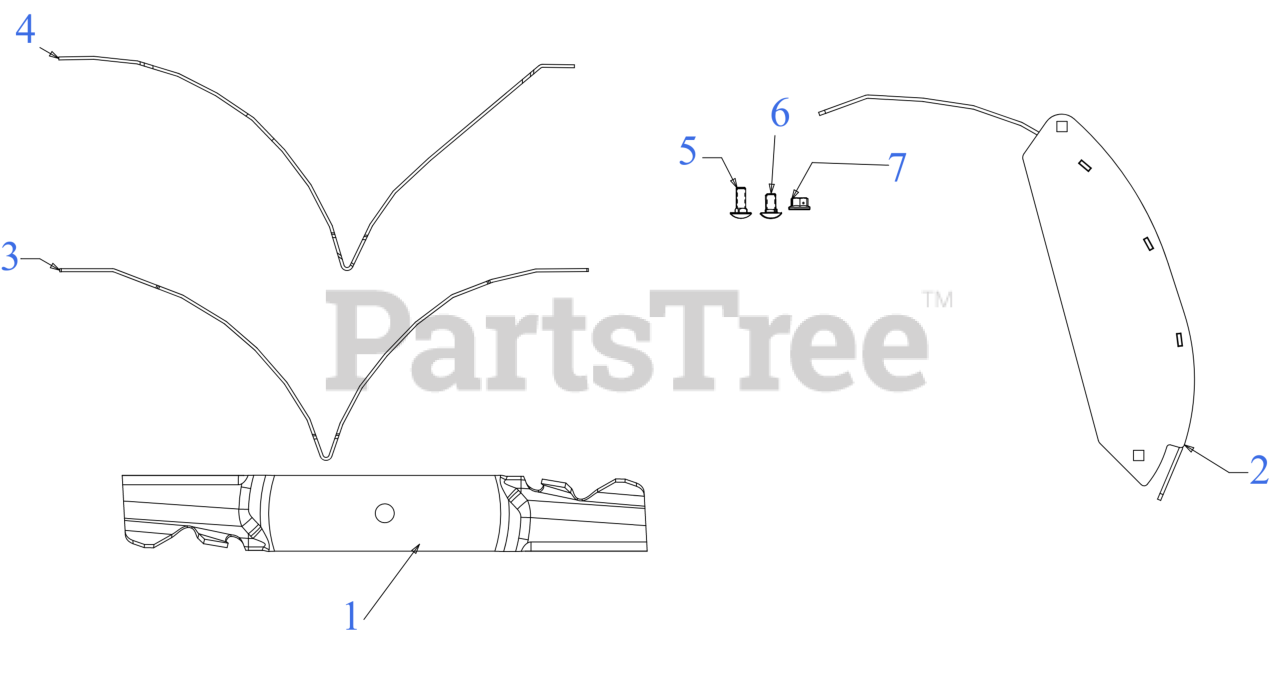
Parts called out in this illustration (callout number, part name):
1	21" XTREME BLADE
2	60" DISCHARGE MULCH BAFFLE
3	MULCH BAFFLE (LEFT)
4	60" MULCH BAFFLE (CENTER)
5	CARRIAGE BOLT 3/8-16 x 1.00 GR5
6	CARRIAGE BOLT 3/8-16 x .75
7	NUT-CTRLCK FLG HEX
